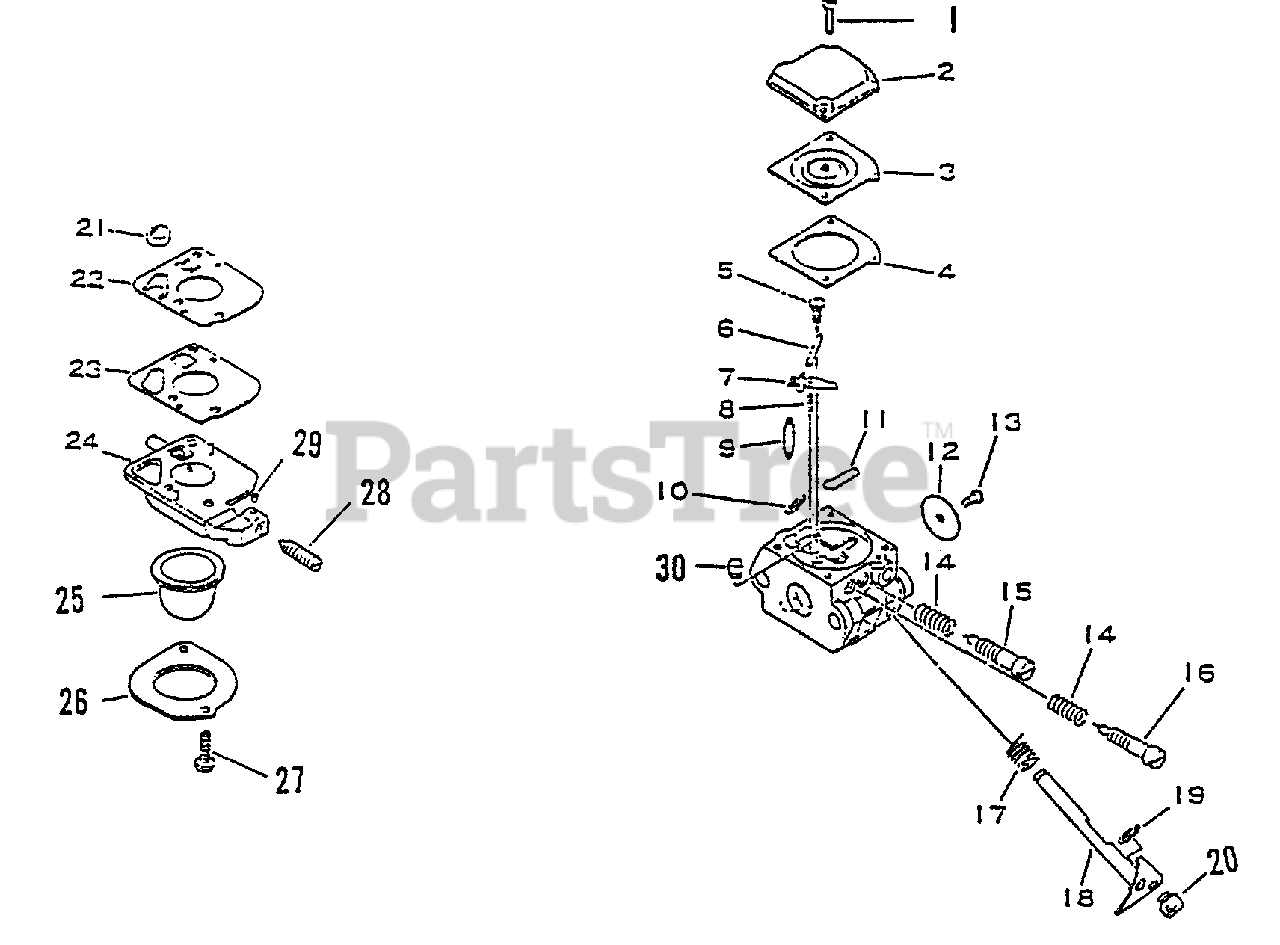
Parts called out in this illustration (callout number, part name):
2	COVER, DIAPHRAGM
3	DIAPHRAGM
4	GASKET, DIAPHRAGM
5	SCREW
6	PIN, METERING LEVER
7	LEVER, METERING
8	SPRING
9	VALVE, NEEDLE
11	PLUG, WELCH
12	VALVE, THROTTLE
14	SPRING, NEEDLE
15	NEEDLE, HIGH SPEED
16	NEEDLE, LOW SPEED
17	SPRING, THROTTLE RETURN
18	SHAFT, THROTTLE
21	STRAINER
22	DIAPHRAGM, FUEL PUMP
23	GASKET, PUMP
24	COVER, PUMP
25	BULB, PURGE
26	RETAINER
28	SCREW, IDLE ADJUST
29	PIECE, FRICTION
30	NOZZLE, CHECK VALVE
